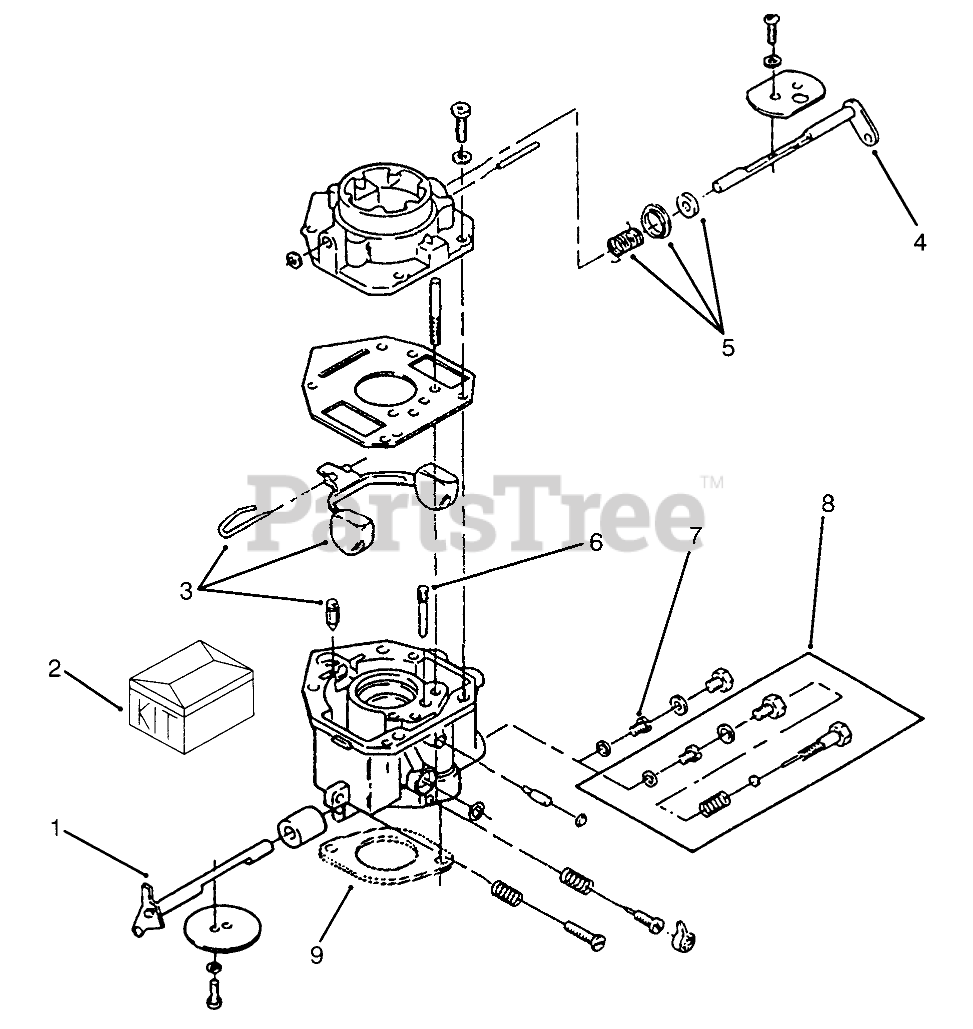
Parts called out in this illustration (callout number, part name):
1	Kit-Shaft,Throttle (Includes Valve Setscrew,Air Filter,& Throttle Valve)
2	Kit-Repair (Includes Screw & Plug Package,Gasket Package,Float Valve,Idle Adj. Needle & Spring,Mounting Gaskets,Idle Limit Cap)
3	Kit-Float (Includes Float,Pin & Valve)
4	Kit-Shaft, Choke (Incl. Choke Valve, Valve Setscrew, & Air Filter)
5	Kit-Lever, Choke (Incl. Choke Lever Ring,Choke Spring, & Choke Collar)
6	IDLE-JET
7	POWER JET
8	FIXED-JET
9	GASKET-CARBURETOR
